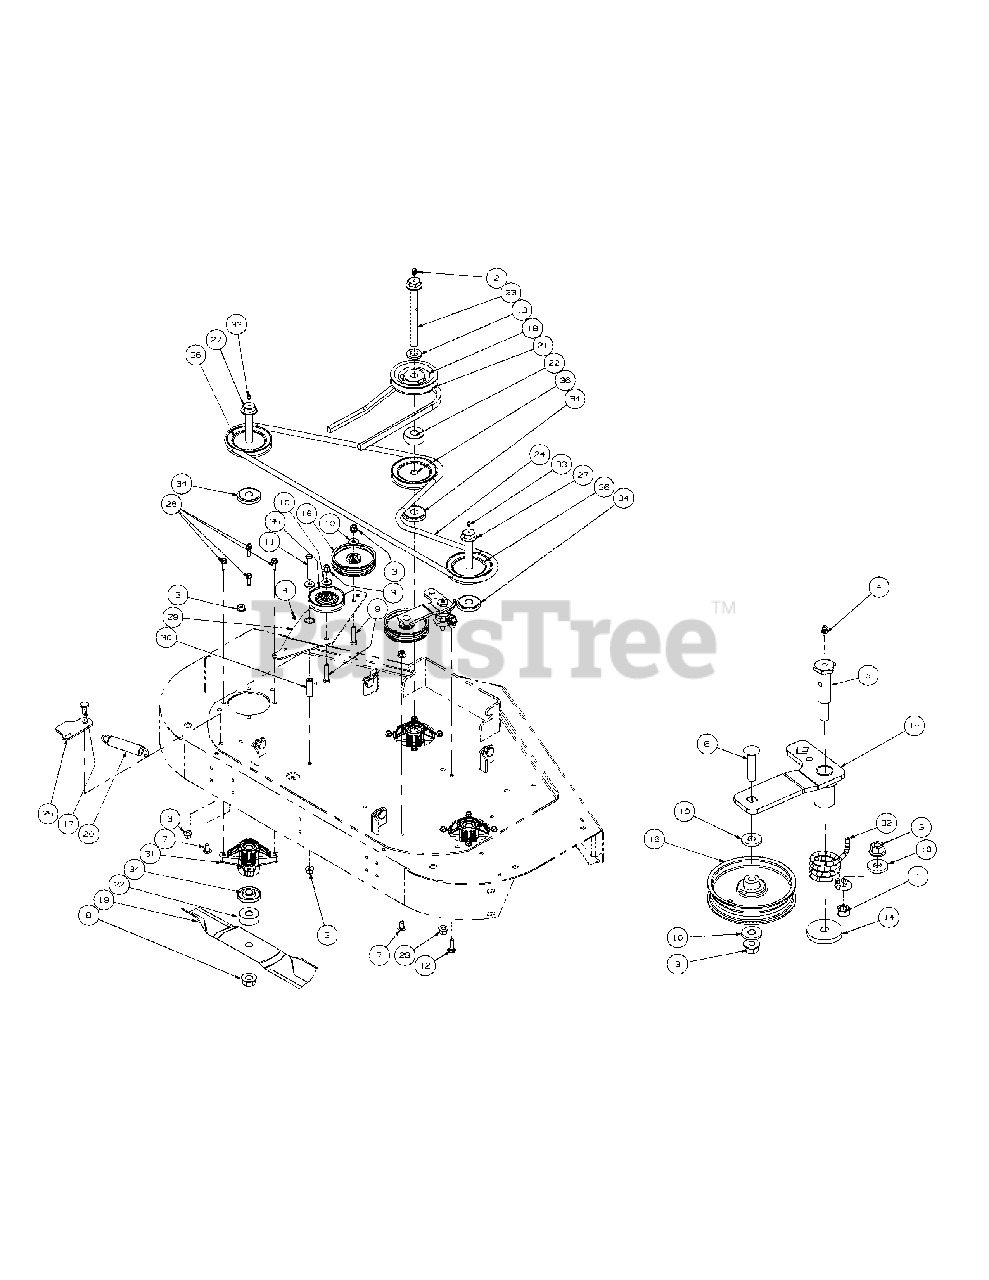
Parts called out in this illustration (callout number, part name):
1	Hex Nut 3/8-16
2	Grease Fitting, 90
3	Hex Nut, 3/8-16 Flange Lock
4	Grease Fitting, 1/4-28 x 3/16
5	Shoulder Screw, 7/16-14
6	Hex Carriage Screw, 3/8-16, 1.75
7	Carriage Bolt 3/8-16 x .75
8	Hex Flange Nut, 3/4-16
9	Hex Cap Screw, 3/8-16 x 1.750
10	Flat Washer, .406 ID x 1.0 OD x .105
11	Hex Cap Screw 3/8-16 x 2.75
12	Carraige Screw, 3/8-16 x 1.25
13	Spacer, .812 ID x .218
14	Flat Washer, 7/16 ID x 1.75 OD
15	Idler Arm Assembly, Deck Spindle includes:
16	Flat Pulley
17	Shoulder Screw, .50 x .27, 3/8-16
18	V-Pulley, 4.75 OD
19	Hi-Lift Blade, 17.0
20	Extension Spring, .98 OD x 5.00
21	V-Belt, B-Section
22	Spacer .760 ID x 2.00 OD x 0.790
23	Spindle Bolt, 3/4-16 x 7.155
24	V-Belt, A-Section
25	Spring Tension Rod Assembly
26	Self Tapping Screw 5/16-18 x 1.00
27	Spindle Bolt 3/4-16 x 5.37
28	Nut, 7/16-20, FlangeLock
29	Idler Arm Assembly, Double, includes:
30	Spacer, .39 ID x .625 OD x 1.875
31	Spindle Assembly
32	Idler Torsion Spring
33	Grease Fitting
34	Spindle Spacer
35	V-Pulley, 3.50 OD
